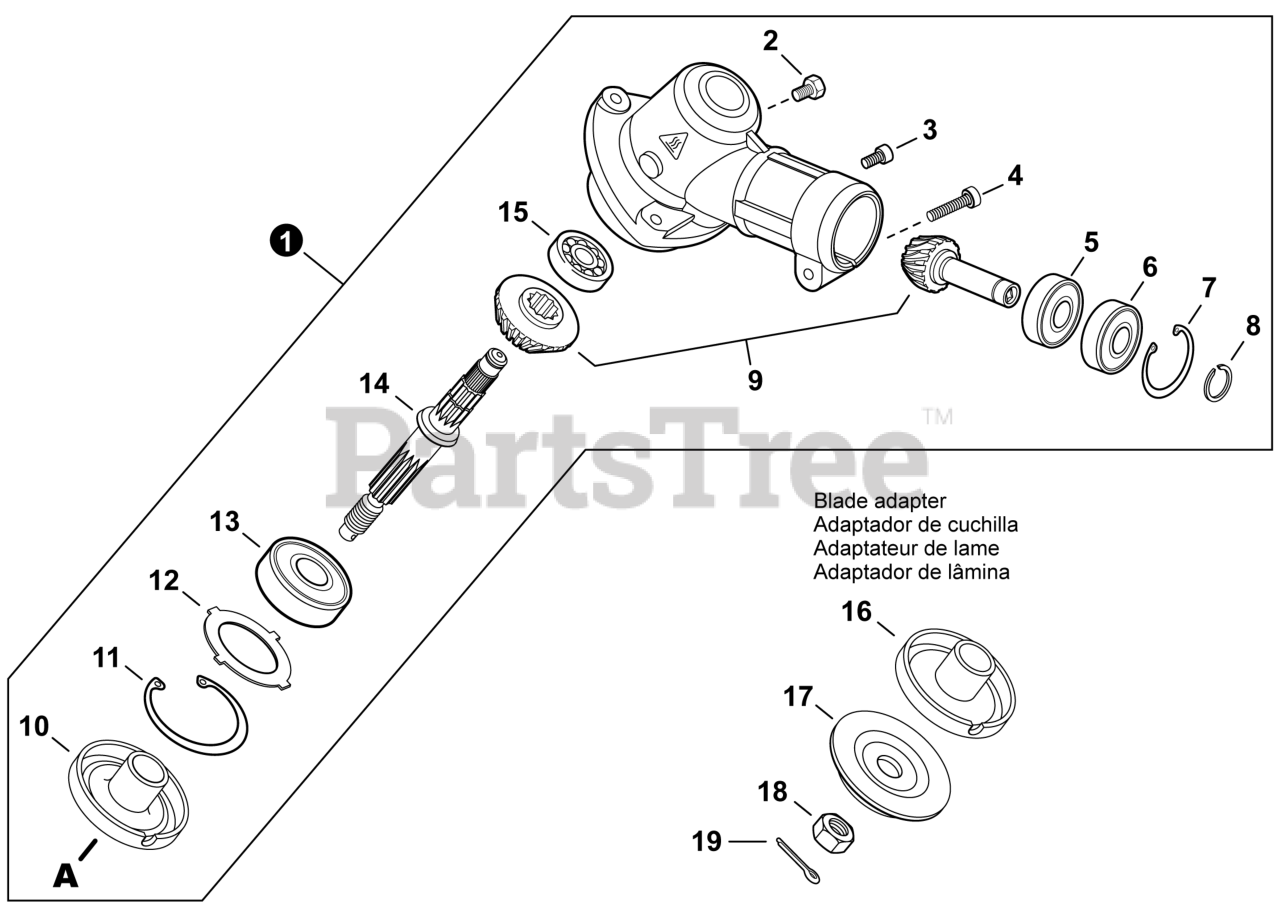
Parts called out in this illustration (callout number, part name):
1	GEAR CASE ASSY
2	BOLT M8x8
3	BOLT, TORX 5x12
4	BOLT, TORX 5x25
5	BEARING, BALL 609A
6	BEARING, BALL 609ZA
7	RING, SNAP 25
8	RING, SNAP 9
9	GEAR SET
10	PLATE, ADAPTOR - UPPER
11	RING, SNAP 32
13	BEARING, BALL 6201
14	SHAFT, GEAR
15	BEARING, BALL 629A
16	PLATE, ADAPTOR - UPPER
17	PLATE, ADAPTOR - LOWER
19	PIN, COTTER 2x22
